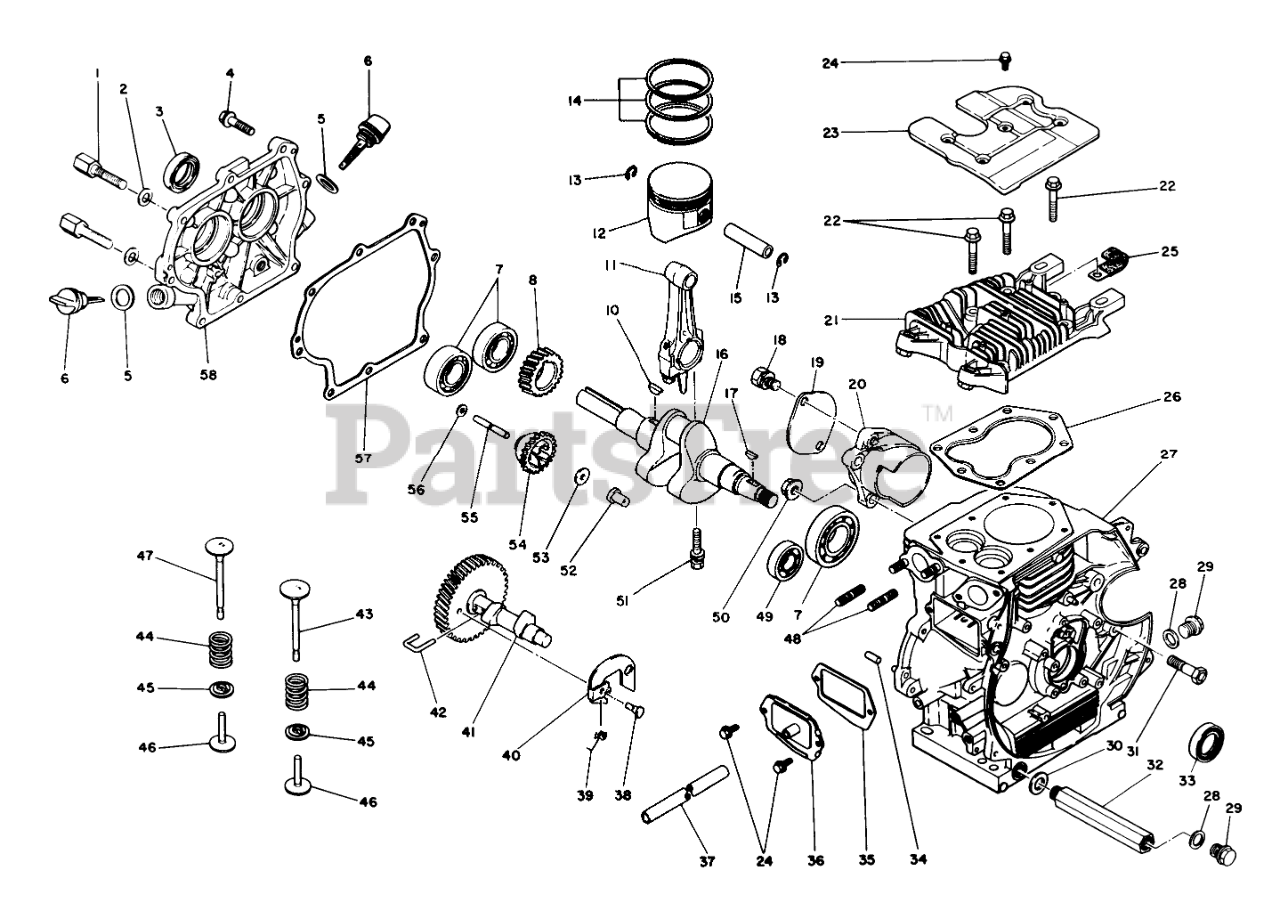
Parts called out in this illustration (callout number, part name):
2	WASHER
3	OIL SEAL
5	GASKET
6	Gauge-Oil (Incl.Ref. #5)
7	BEARING
8	CRANKSHAFT GEAR
11	Connecting Rod Assembly (Std.)(Incl. Ref #51)
12	Piston Assembly (Std.)(Incl.Ref. #15)
13	PISTON PIN CLIP
14	PISTON RING SET
15	PISTON PIN
16	CRANKSHAFT
18	BOLT & WASHER
19	COVER
20	BRACKET
21	CYLINDER HEAD
23	COVER-HEAD
25	CLAMP
26	HEAD GASKET
27	Cylinder Block Assembly (Incl.Ref. #34 & 48)
28	GASKET
29	DRAIN PLUG
30	GASKET
32	NIPPLE
33	OIL SEAL
35	GASKET=BRTHR
36	BREATHER VALVE ASM
37	BREATHER TUBE
39	SPRING
40	FLYWEIGHT
41	Camshaft Assembly (Incl.Ref. #38, 39, 40 & 42)
43	INT VALVE
44	VALVE SPRING
45	RETAINER VALVE
46	TAPPET
47	EXHAUST VALVE
49	BEARING
51	CONNECTING ROD BOLT
52	SLIDER-GOV
53	SPACER
54	Governor Gear Assembly (Incl. Ref. #52)
55	SHAFT-GOV.
56	WASHER
57	CRANKCASE GASKET
58	CRANKCASE COVER
